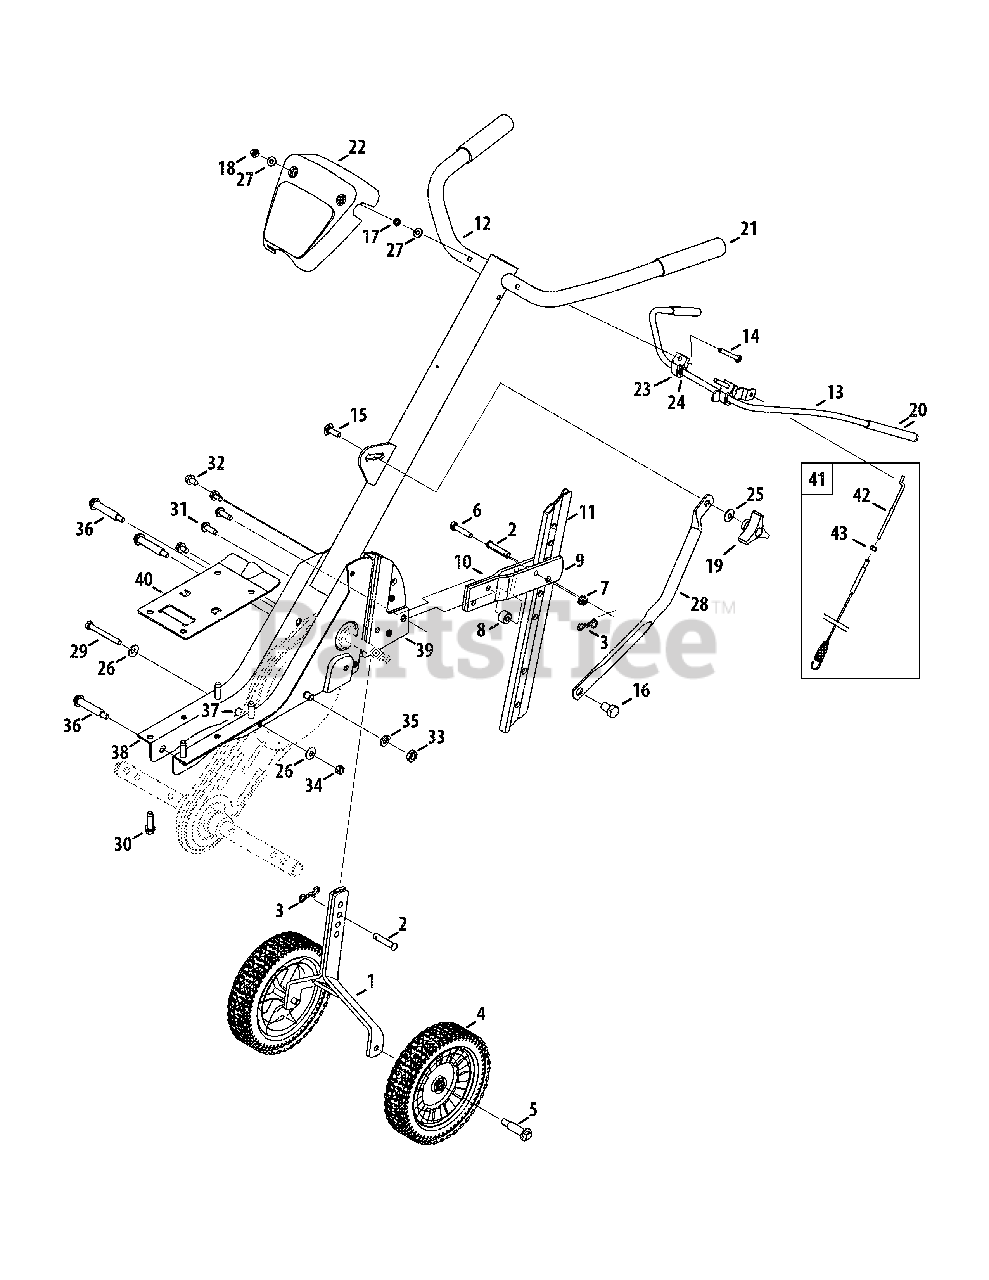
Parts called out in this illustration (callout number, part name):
1	Wheel Bracket Assembly
2	Clevis Pin, .375 x 1.75
3	Cotter Pin
4	Wheel Assembly, 8 x 1.75
5	Shoulder Screw, 3/8-16 x .496 x 1.445
6	Hex Screw, 5/16-18 x 1.50
7	Flange Lock Nut, 5/16-18
8	Spacer, .325 x .75 x .520
9	LH Tail Bracket
10	RH Tail Bracket
11	Depth Bar
12	Handle Assembly
13	Clutch Bail
14	Hex Screw, 1/4-20 x 2.25
15	Carriage Screw, 5/16-18 x 1.00
16	Hex Screw, 1/2-20 x .750
17	Jam Nut, 1/4-20
18	Lock Nut, 1/4-20
19	Handle Knob
20	Grip, Clutch Bail
21	Grip, Handle
22	Handle Cover
23	Clutch Bail Holder
24	Flat Washer, .385 x .62 x .063
25	Bell Washer, .340 x .872 x .060
26	Bell Washer, .331 x .827 x .098
27	Flat Washer, .271 x .630 x .065
28	Handle Brace
29	Hex Screw, 5/16-18 x 3.00
30	SEMS Screw, 3/8-16
31	Self-Tapping Screw, 5/16-18 x 1.00
32	Hex Washer Screw, 5/16-18 x .750
33	Jam Nut, 7/16-20
34	Flange Lock Nut, 5/16-18
35	Lock Washer, 7/16
36	Shoulder Screw, 5/16-18 x .475 x 2.11
37	Spacer, .47 x .96
40	Engine Mounting Plate
41	Forward Clutch Cable
42	Z-Fitting (inc. #43)
43	Jam Nut
